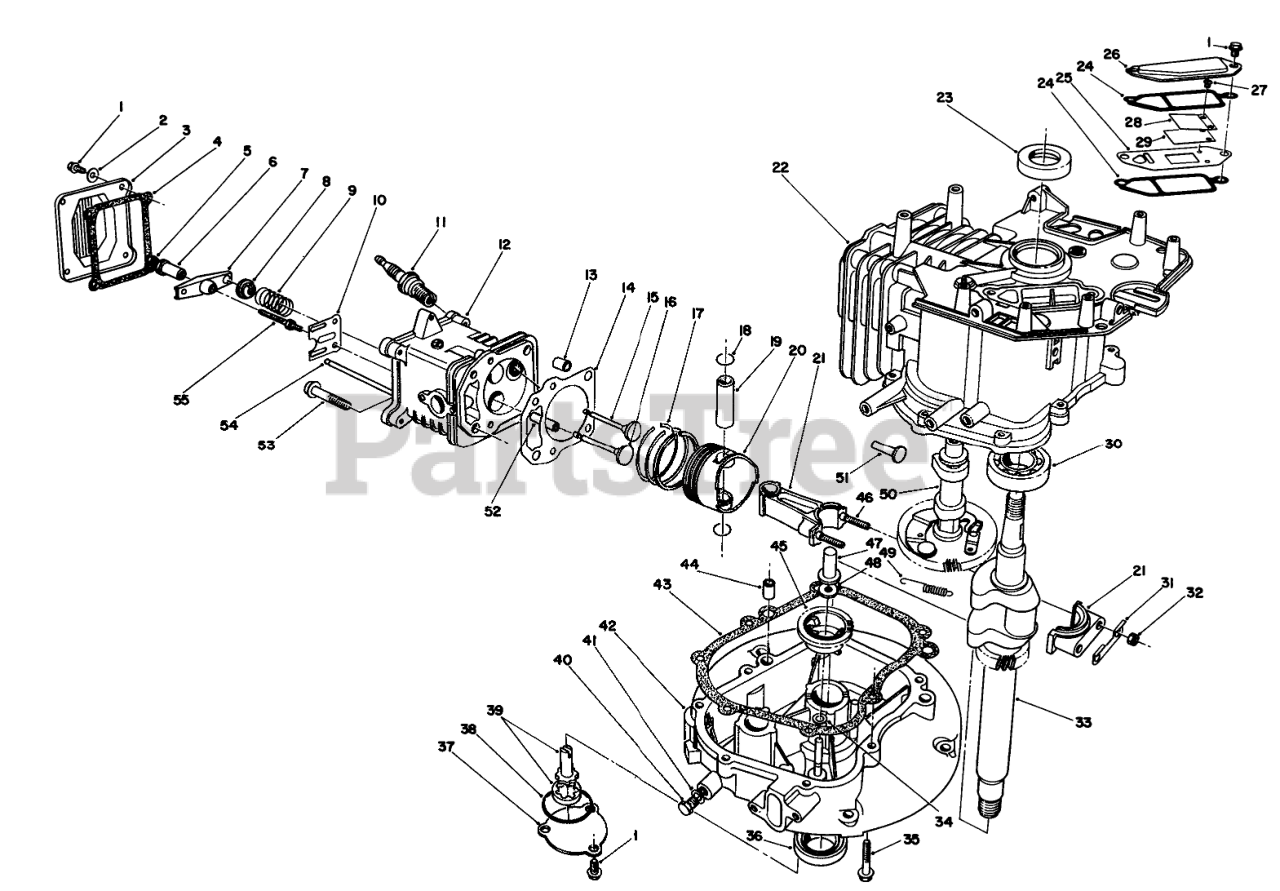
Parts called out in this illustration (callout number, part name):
2	WASHER
3	COVER
4	GASKET
6	PIVOT
8	RETAINER
9	SPRING
10	GUIDE
11	SPARK PLUG
12	Head-Cylinder (Incl. Ref. #52)
14	GASKET
15	VALVE-INTAKE
16	VALVE-EXHAUST
17	RING SET
18	CIRCLIP
20	PISTON
21	Connecting Rod Assembly (Incl. Ref. #31, 32 & 46)
22	Block-Engine (Incl. Ref. #23 & 30)
24	GASKET
25	Plate-Breather
26	COVER
27	Screw-Reed Valve
28	Retainer-Reed Valve
29	Valve-Reed
30	BEARING
31	Plate-Lock
33	CRANKSHAFT
34	WASHER
36	Oil Seal
37	COVER
38	O-RING
39	OIL PUMP
40	OIL DRAIN PLUG
41	GASKET
42	Crankcase
43	GASKET
45	GOVERNOR FLYWEIGHT ASM
47	PLUNGER
48	WASHER
49	SPRING
50	Camshaft Assembly (Incl. Ref. #49)
51	TAPPET
52	GUIDE
